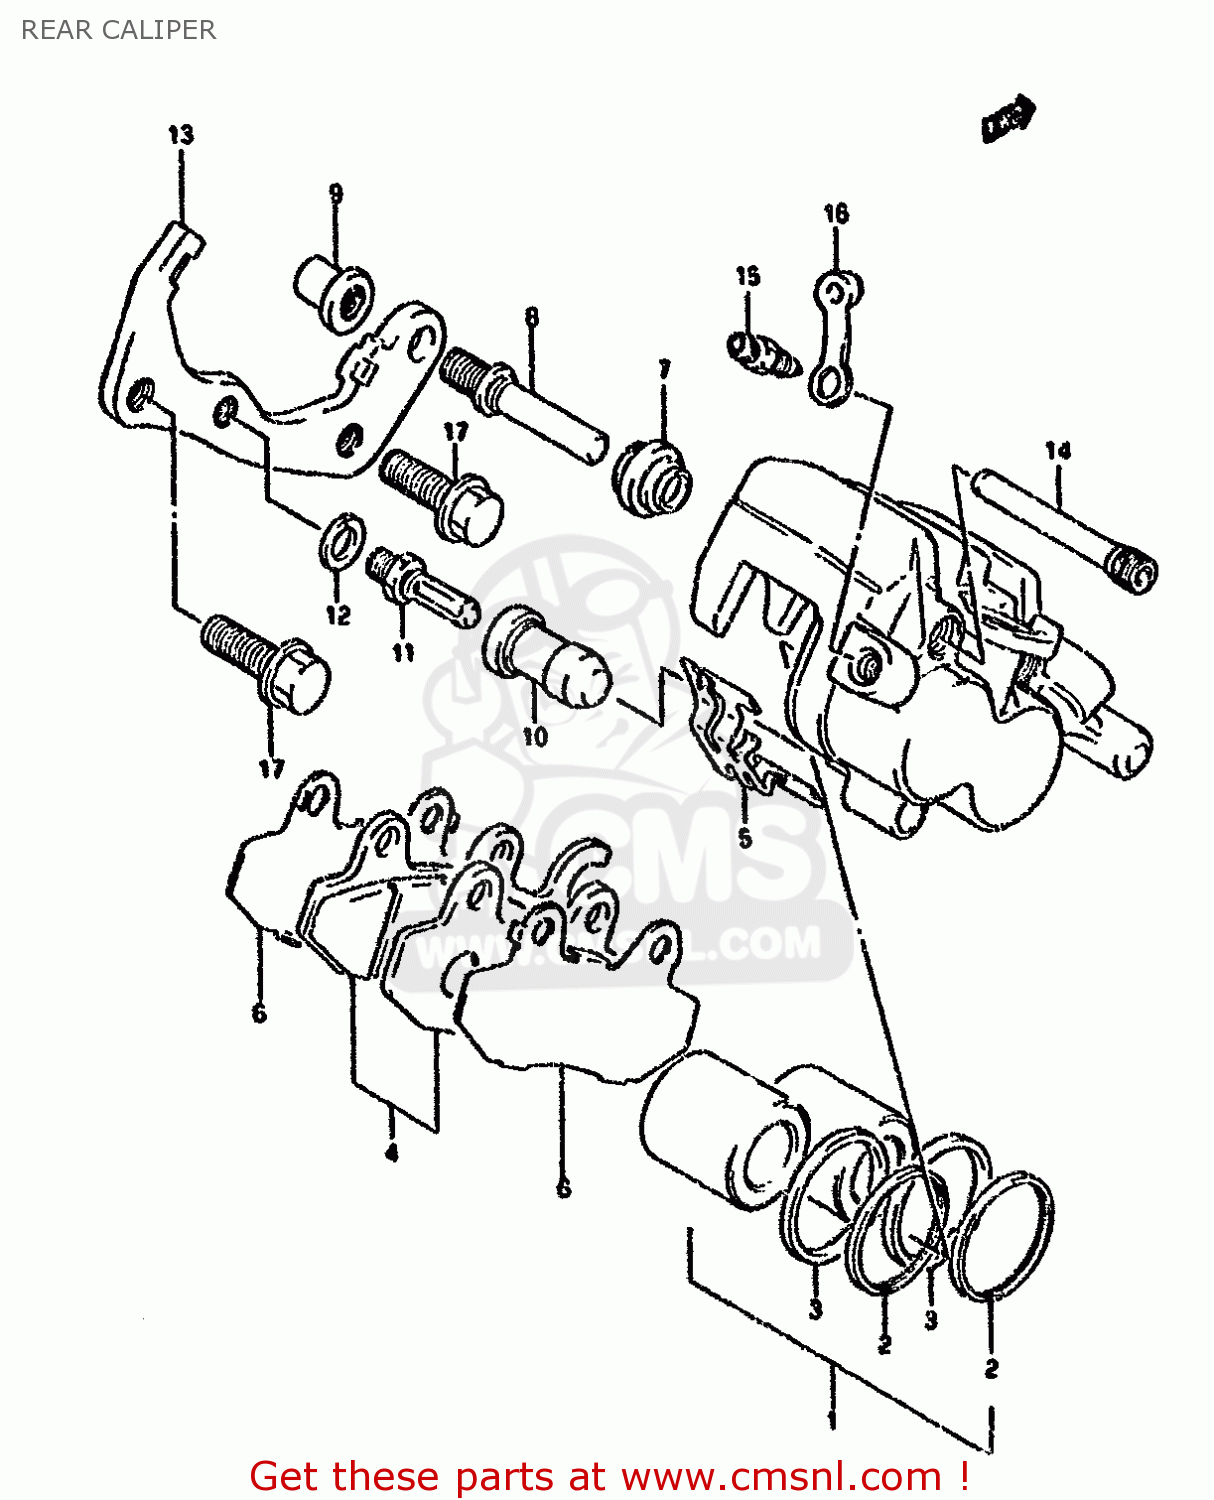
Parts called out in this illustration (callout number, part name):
1	PISTON SET
2	SEAL,PISTON
3	SEAL,DUST
4	PAD SET (NAS)
5	SPRING
6	SHIM
7	BOOT
8	PIN,SLIDE
9	NUT
10	BOOT
11	BOLT,PIN
12	WASHER,WAVE
13	BRACKET
14	PIN,HANGER
15	BLEEDER
16	CAP,BLEEDER
17	BOLT 10X23
